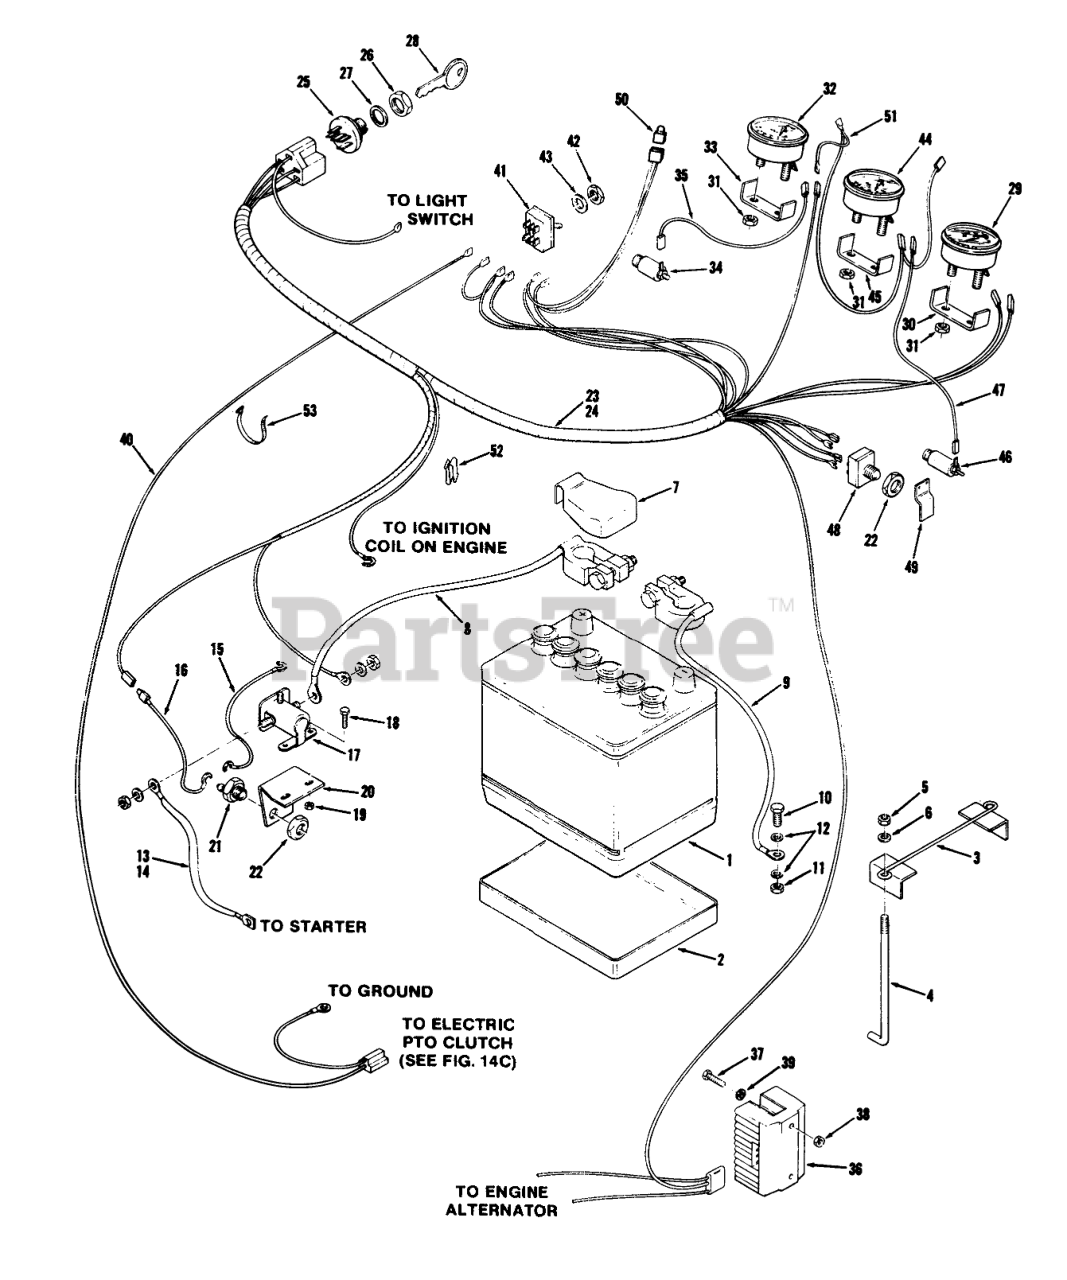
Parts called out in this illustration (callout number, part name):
1	Battery
2	Battery Box
3	Assy-Hold Down
4	Hook-Battery Retainer
5	Nut
7	Cover Battery Term
8	ASSY-WIRE SOLENOID
9	ASSY-WIRE
10	Bolt
11	Nut
12	Washer
13	Cable
14	Cable
15	WIRE ASSY
16	Assy-Wire
17	Solenoid
18	Bolt
19	Nut
20	Bracket
21	SWITCH SAFETY
22	NUT-SPECIAL 9/16-18
24	Wiring Harness
25	SWITCH-IGNITION
27	LOCKWASHER
28	Knife Section, L.H.
29	AMMETER W/CLAMP
30	Clamp
31	HEX NUT 10-32 E.S.
32	Gauge-Oil Temp
33	CLAMP MOUNTING
34	Assy-Thermistor
35	Assy-Wre
36	REGULATOR-RECTIFIER
37	Bolt
38	Nut
40	Assy-Wire and Plug
41	SWITCH CLUTCH
42	NUT-HEX
43	Nut, Knurled
44	Gauge-Oil Pressure
45	CLAMP MOUNTING
46	SENDER-OIL PRESSURE
47	Assy-Wire Sender
48	SWITCH-CLUTCH
49	CLIP-SWITCH
50	WASHER
51	Assy-Wire Gauge
52	Clip
53	PLASTIC TIE
